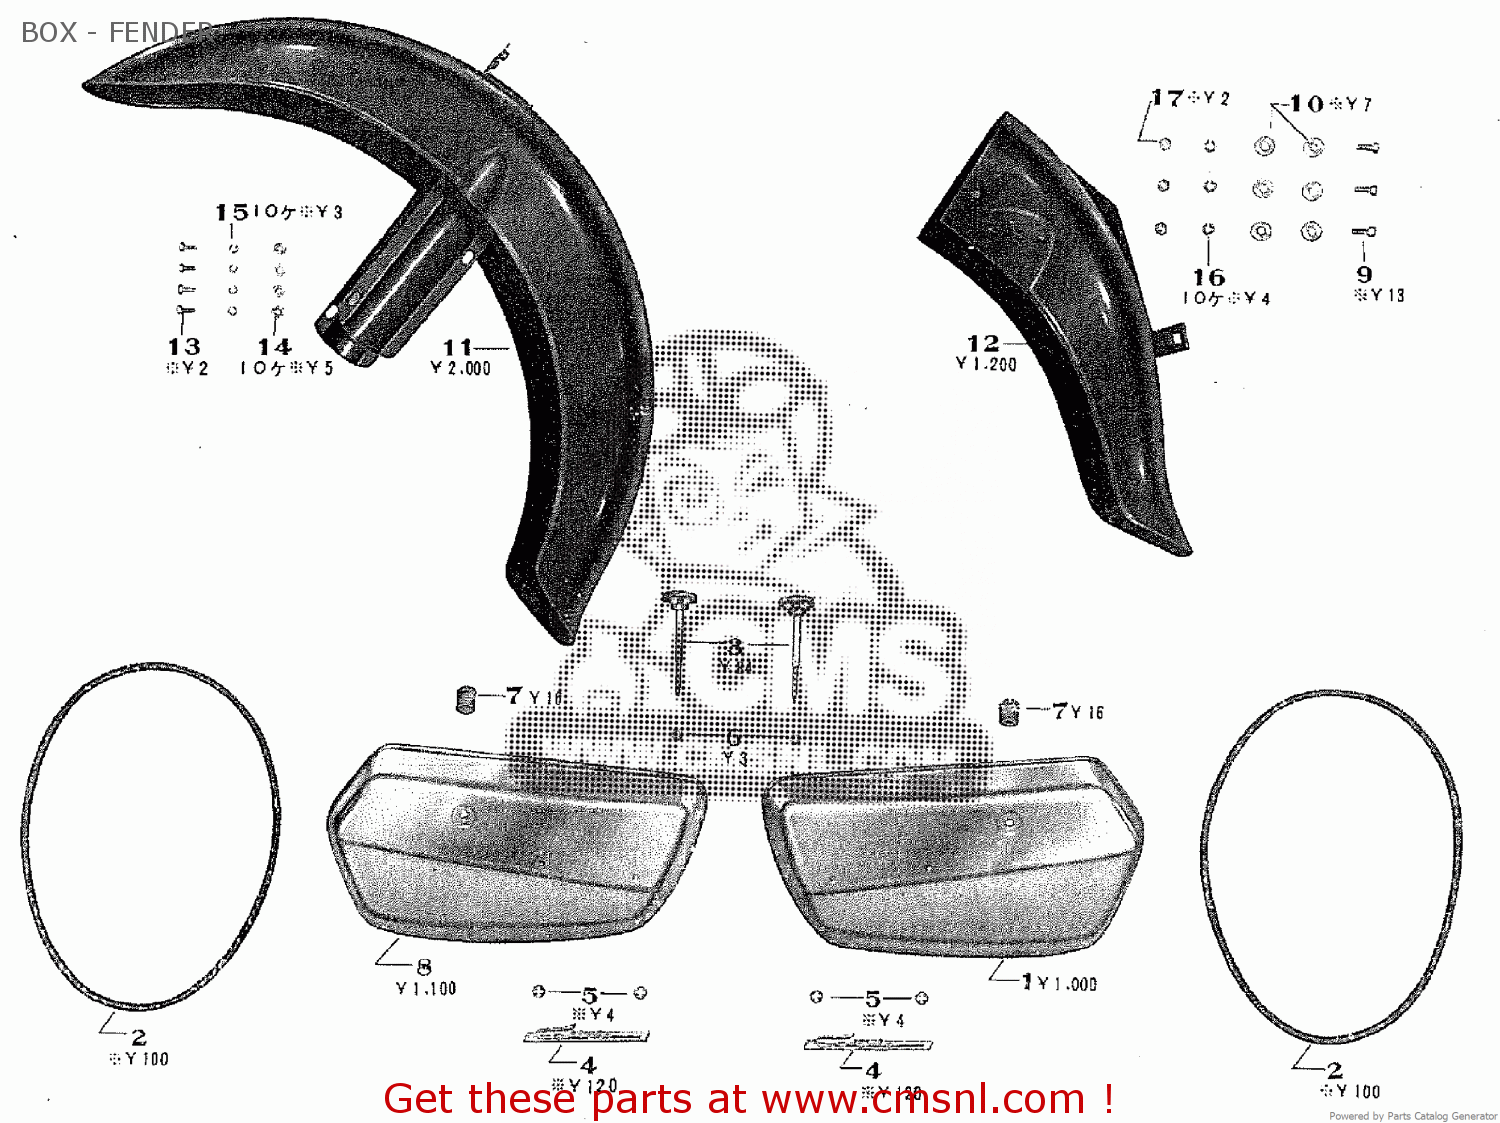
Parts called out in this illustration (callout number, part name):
1	ELECTRICK BOX COMP.
2	BOX PACKING
3	BOX NOB COMP.
4	COVER ACCESSORY
5	COVER ACCESSORY SET CLIP
6	BOX NOB NUT
7	BOX SET BOSS
8	TOOL BOX COMP.
9	BOLT
10	WASHER
11	FRONT FENDER COMP.
12	REAR FENDER COMP.
13	5X12 HEXAGON BOLT
14	5MM PLANE WASHER
15	5MM SPRING WASHER
16	6MM SPRING WASHER
17	6MM HEXAGON NUT
